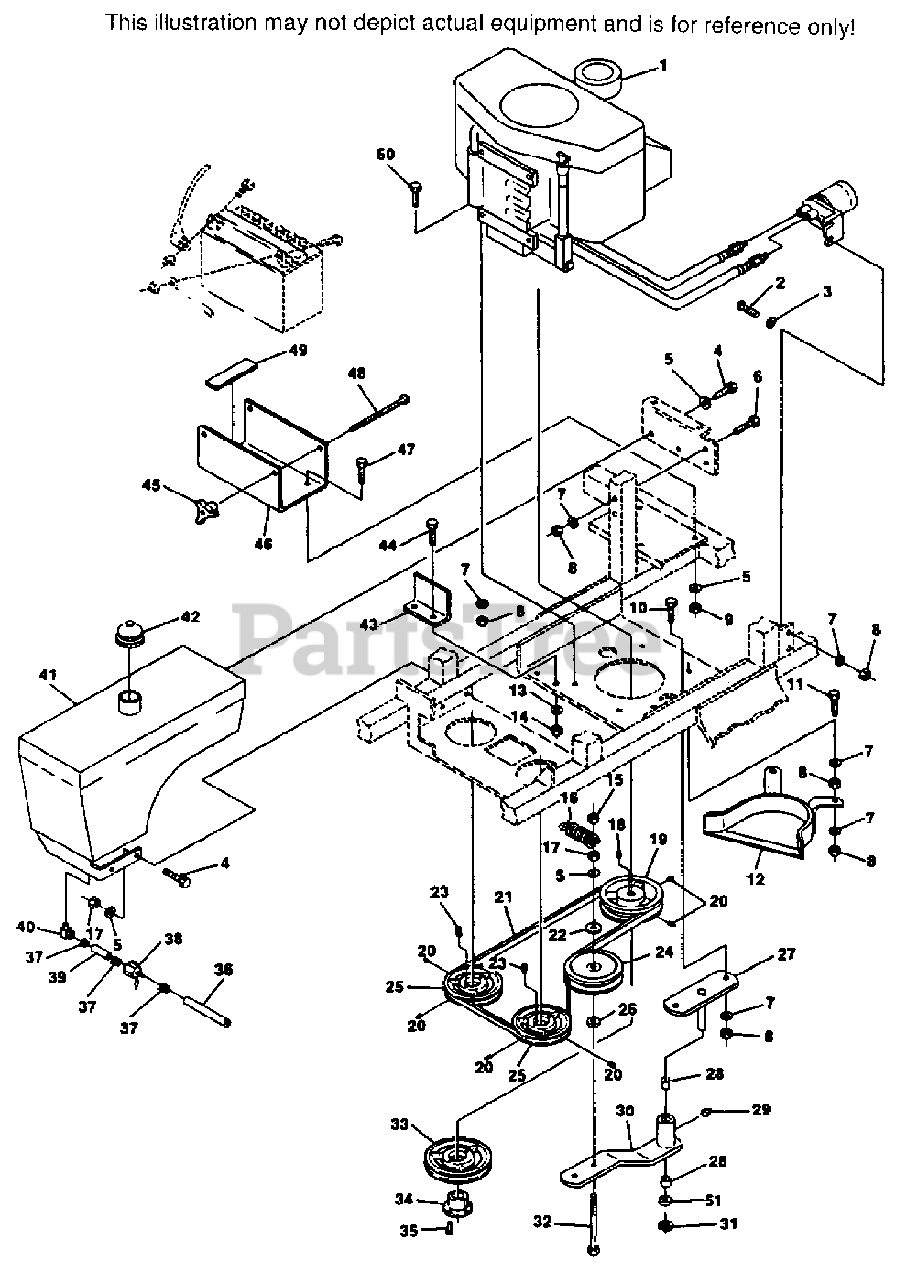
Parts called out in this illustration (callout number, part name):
1	ENGINE, 20 HP KOHLER
12	BELT GUIDE
16	SPRING, IDLER ARM
18	KEY, 1/4 X 1/4 X 2-1/2
19	PULLEY, ENGINE - PUMP DRIVE
20	SETSCREW, 5/16-18 X 3/8 HEX SOCKET HEAD
21	BELT, PUMP DRIVE
23	KEY, WOODRUFF # 61
24	PULLEY, IDLER PUMP DRIVE
25	PULLEY, PUMP SHAFT
26	FLAT WASHER, 3/8 X 12 GA.
27	IDLER PIVOT
28	BUSHING
29	GREASE FITTING
30	IDLER ARM(INCLUDES BUSHINGS & GREASE FTG.)
31	RETAINING RING, 3/4 EXTERNAL "E"
32	HEX HEAD BOLT, 3/8-16 X 3-1/2 FULL THREAD
33	PULLEY, ENGINE - CUTTER DRIVE
34	HUB, PULLEY
36	FUEL HOSE, 10" LONG
37	CLAMP, FUEL HOSE
38	FUEL SHUT OFF VALVE
39	FUEL HOSE, 1-1/4" LONG
40	ELBOW, 90 DEG. MALE 1/4 NPT TO 1/4 HOSE
41	FUEL TANK(INCLUDES CAP)
42	FUEL TANK CAP(METAL FUEL TANK)
42	FUEL TANK CAP(PLASTIC FUEL TANK)
43	HEAT DEFLECTOR
45	ELASTIC STOP WINGNUT, 1/4-20
46	PLATE, BATTERY BOX
49	PAD, BATTERY SUPPORT
51	WASHER, 3/4"
